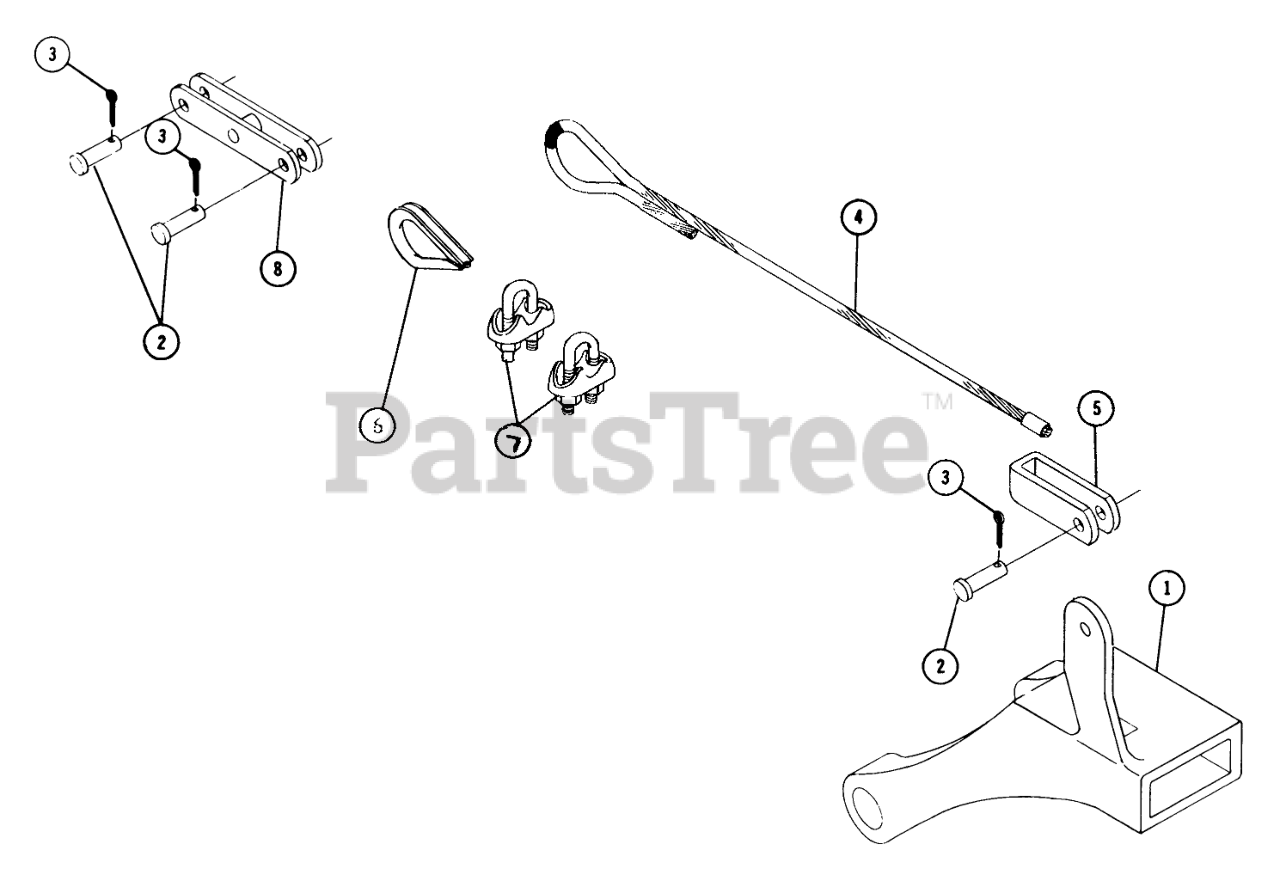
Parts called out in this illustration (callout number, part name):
1	Hitch
2	Pin
3	Cotter Pin
4	CABLE-LIFT LVR HITCH
5	Clevis
6	Thimble
7	U BOLT
8	ASSEMBLY CLEVIS
